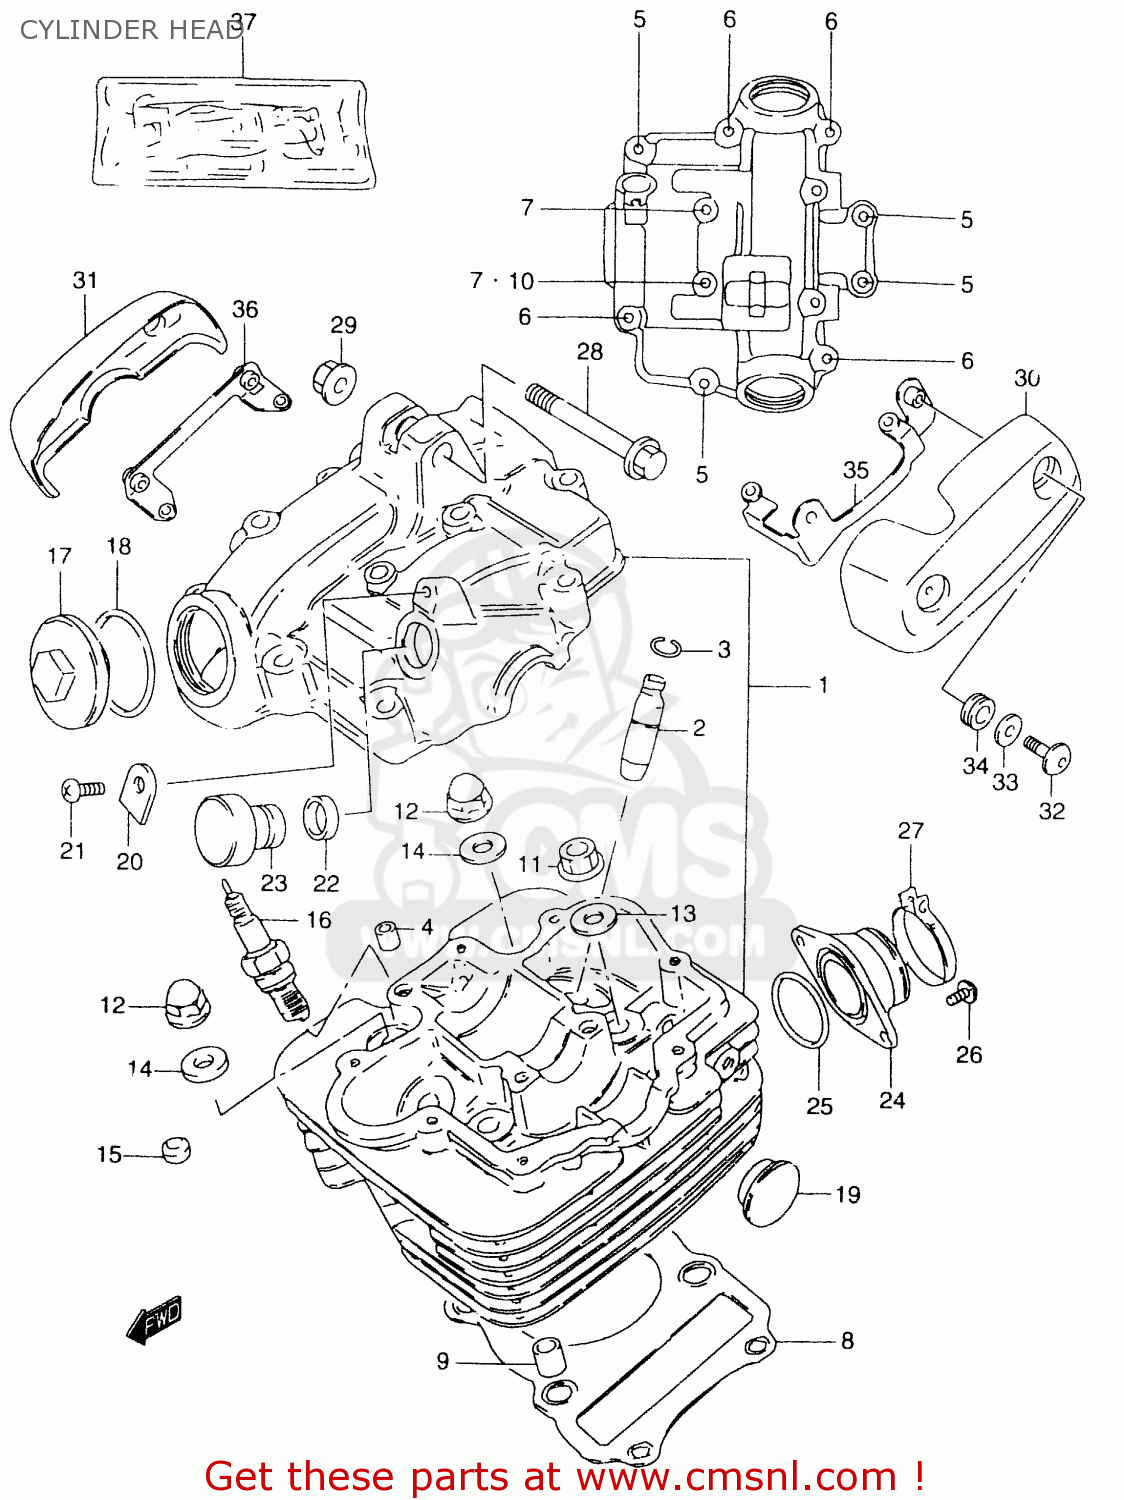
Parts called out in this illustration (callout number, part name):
1	HEAD ASSY,CYLINDER
2	GUIDE,VALVE
3	RING,SNAP
4	PIN(6.2X8X11)
5	BOLT
6	BOLT
7	BOLT
8	GASKET,CYLINDER HEAD (NAS)
9	PIN
10	GASKET(5.8X13X1.2) (NAS)
11	NUT
12	NUT
13	WASHER (8.5X19X2.3)
14	GASKET(8.5X17X2.3) (NAS)
15	PAD,CYLINDER HEAD
16	PLUG,SPARK(DR8EA)
17	CAP,INSPECTION
18	O RING(D:3,ID:29.5)
19	PLUG(OD:22.5)
20	PLATE,TACH DRIVE GEAR SLEEVE
21	SCREW(5X12)
22	SEAL,TACHOMETER DRIVEN
23	PLUG,TACH GEAR SLEEVE HOLE
24	PIPE,INTAKE
25	O RING(D:2.4,ID:31.7)
26	SCREW ,6X16
27	CLAMP
28	BOLT(8X50)
29	NUT
30	CAP,CYLINDER HEAD COVER,L
31	CAP,CYLINDER HEAD COVER,R
32	BOLT
33	WASHER(6.5X24X1.6)
34	CUSHION
35	BRACKET, CAP
36	BRACKET, HEAD CAP RH
37	GASKET SET (NAS)
